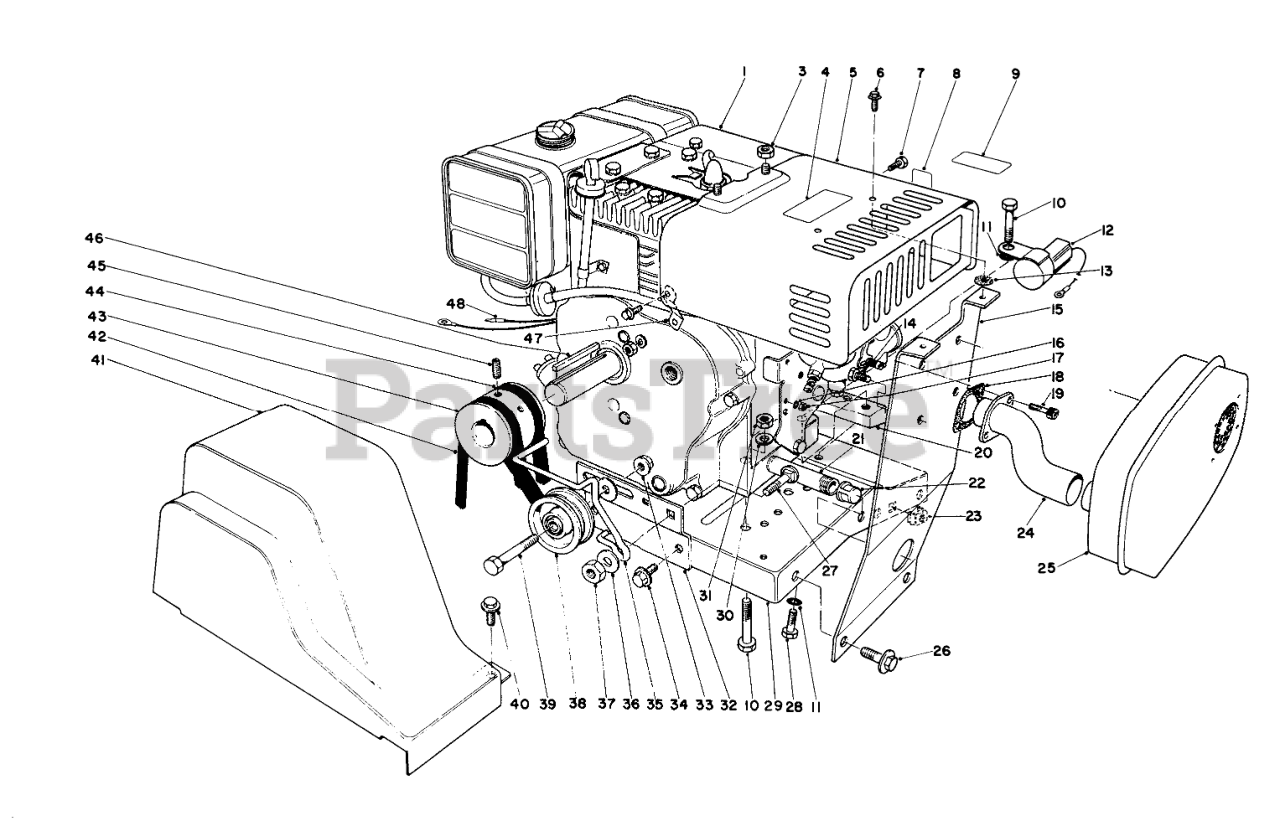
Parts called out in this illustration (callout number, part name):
1	Engine
2	Decal-Hazard
3	NUT-HEX, SIDE DEFORM
4	Decal Hot Surface Warning
5	Heater Box
6	SCREW
8	CHOKE DECAL
9	DECAL SYNCHRO BALANCE
10	SCREW-HH
11	WASHER-LOCK, INTERNAL
12	INTERLOCK MODULE
13	Washer
14	1/4-20 X 1/2 SEMS MS
15	Muffler Mounting Bracket
16	WASHER-LOCK/INT
17	NUT-LOCK
18	Gasket
19	SCREW-HSH
20	Block Engine Mounting
21	NIPPLE-PIPE
22	Pipe Cap
23	Retained Nut
24	EXHAUST PIPE
25	Muffler
26	SCREW-HH
27	SCREW-CARR
28	SCREW-HH
29	Base-Engine
30	WASHER-PLAIN
31	NUT-LOCK, NI
32	BELT IDLER BRKT
33	NUT-HHF, WHIZ
34	SCREW-HHFTF
35	BELT GUIDE
36	WASHER-FLAT
37	NUT-HEX
38	PULLEY B
39	SCREW-HH
40	SCREW-HWH
41	BELT GUARD
42	V-BELT
43	ENGINE PULLEY
44	V-BELT
45	Screw-Set
47	Brace Heater Box
